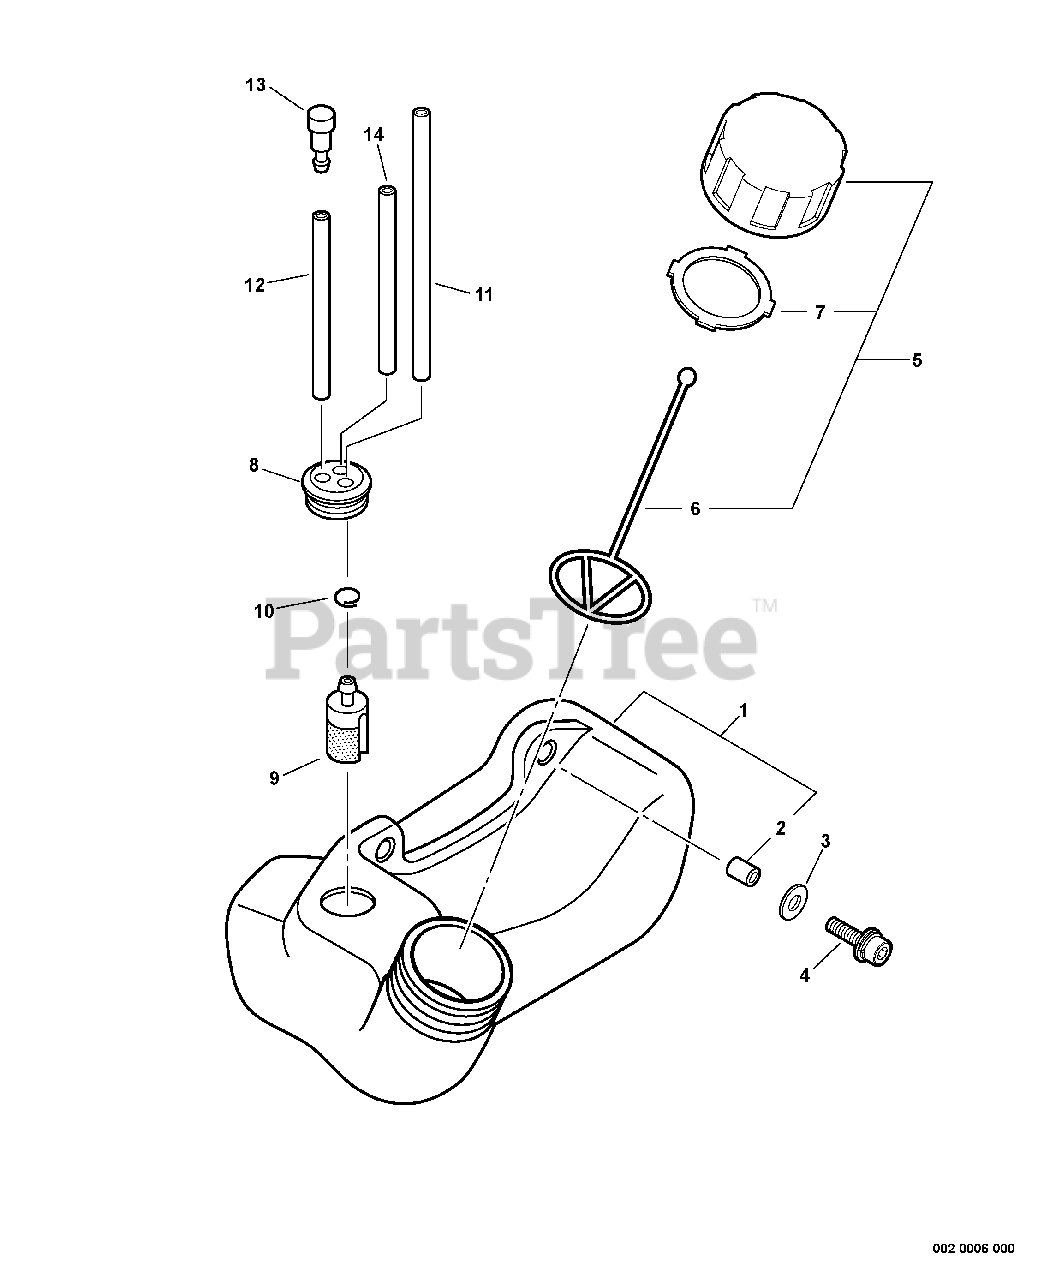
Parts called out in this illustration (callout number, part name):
1	TANK, FUEL
2	SPACER 6.2×7.8×6
3	WASHER 5.5×12×0.8
4	BOLT 5×16
5	CAP ASSY, FUEL
6	CONNECTOR, CAP L= 100 MM
7	GASKET, FUEL CAP
8	GROMMET, FUEL
9	FILTER, FUEL
10	CLIP 6 MM
11	PIPE, FUEL 3x-5x-180
12	PIPE, FUEL 3x-5x-70 BLACK
13	VENT ASSY
14	PIPE, FUEL 3×6×80 CLEAR
